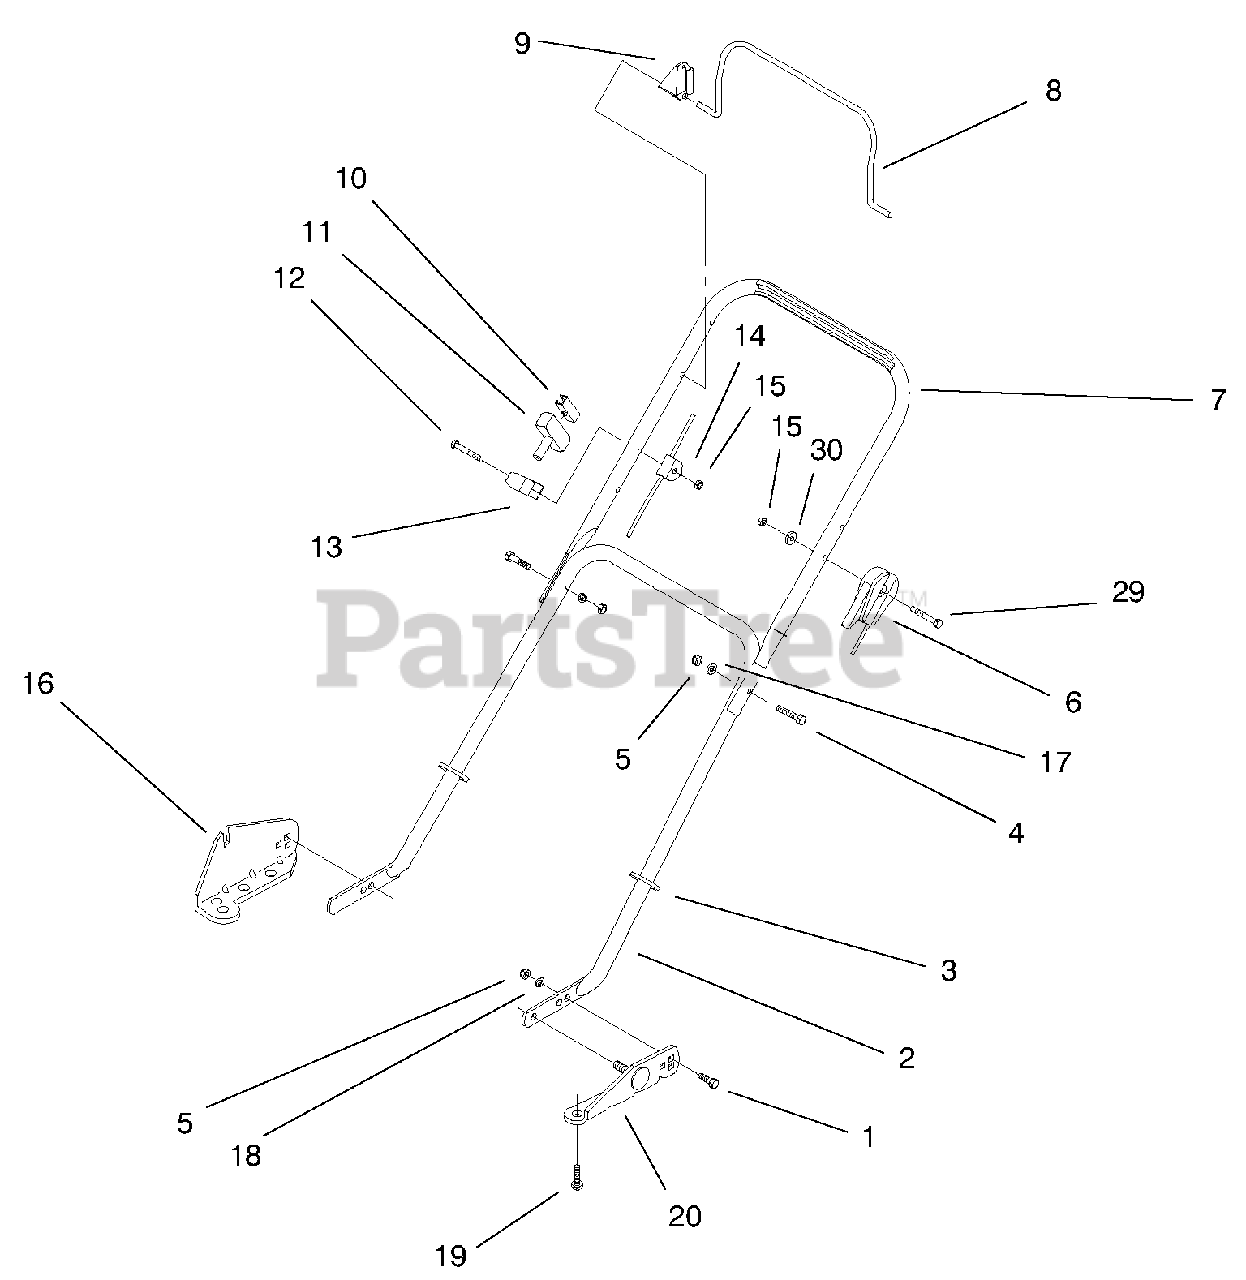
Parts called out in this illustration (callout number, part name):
1	SCREW-CARR
2	Handle Section-Lower
3	STRAP-TIE
4	SCREW-HH
5	NUT-LOCK, NI
6	CABLE-THROTTLE
7	HANDLE-UPPER
8	BAIL CONTROL LEVER ASM
9	STOP-PIVOT
10	CLIP-STARTER
11	HANDLE-START
12	SCREW-HH
13	GUIDE-ROPE
14	CABLE-BRAKE
15	NUT-LOCK, NI
16	RH BRACKET & PIN ASM
17	WASHER - CURVED
18	WASHER-LOCK
20	LH BRACKET & PIN ASM
29	SCREW-HH
30	WASHER
